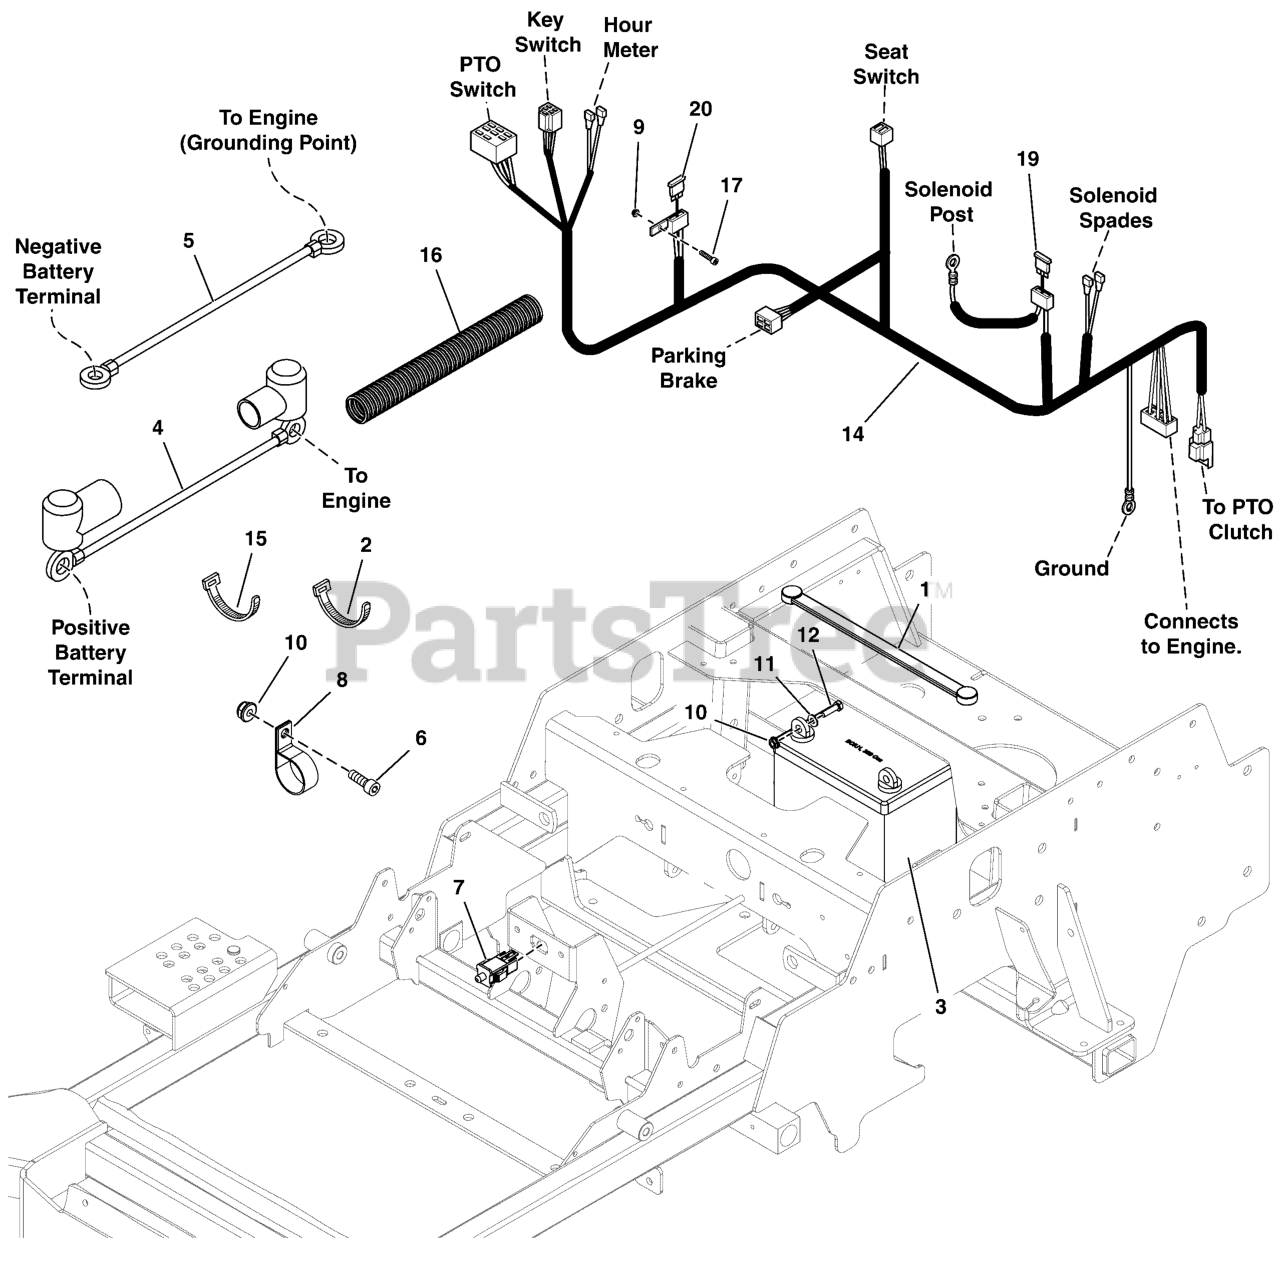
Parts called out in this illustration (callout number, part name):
1	STRAP, Rubber, 13"
2	TIE, 6" Self-Locking
3	BATTERY, WET ( BCIU1, 340 CCA)
4	BATTERY CABLE, POS, 22, 1/4-5/16
5	BATTERY CABLE, NEG, 14, 5/16-13/32
7	SWITCH, DP, NO/NC, Snap-In
8	CLAMP, VINYL INSULATED, 1.00
9	NUT, Nylock, #10-24
10	NUT, Serrated, Flange, 1/4-20, GR5
11	WASHER, Flat, 1/4
12	CAPSCREW, Hex Head, 1/4-20 x 3/4 (stiffener to top of cover)
14	HARNESS, SMALL, ZTR WIRING
15	TIE, SELF-LOCKING, 12"
16	WIRE LOOM, 3/8 ID X 18 IN
17	SCREW, #10-24 X 3/4", ROUND PHILLIPS
19	FUSE, ATO, 20 AMP (SV)
20	FUSE, ATO, 15 AMP (SV)
